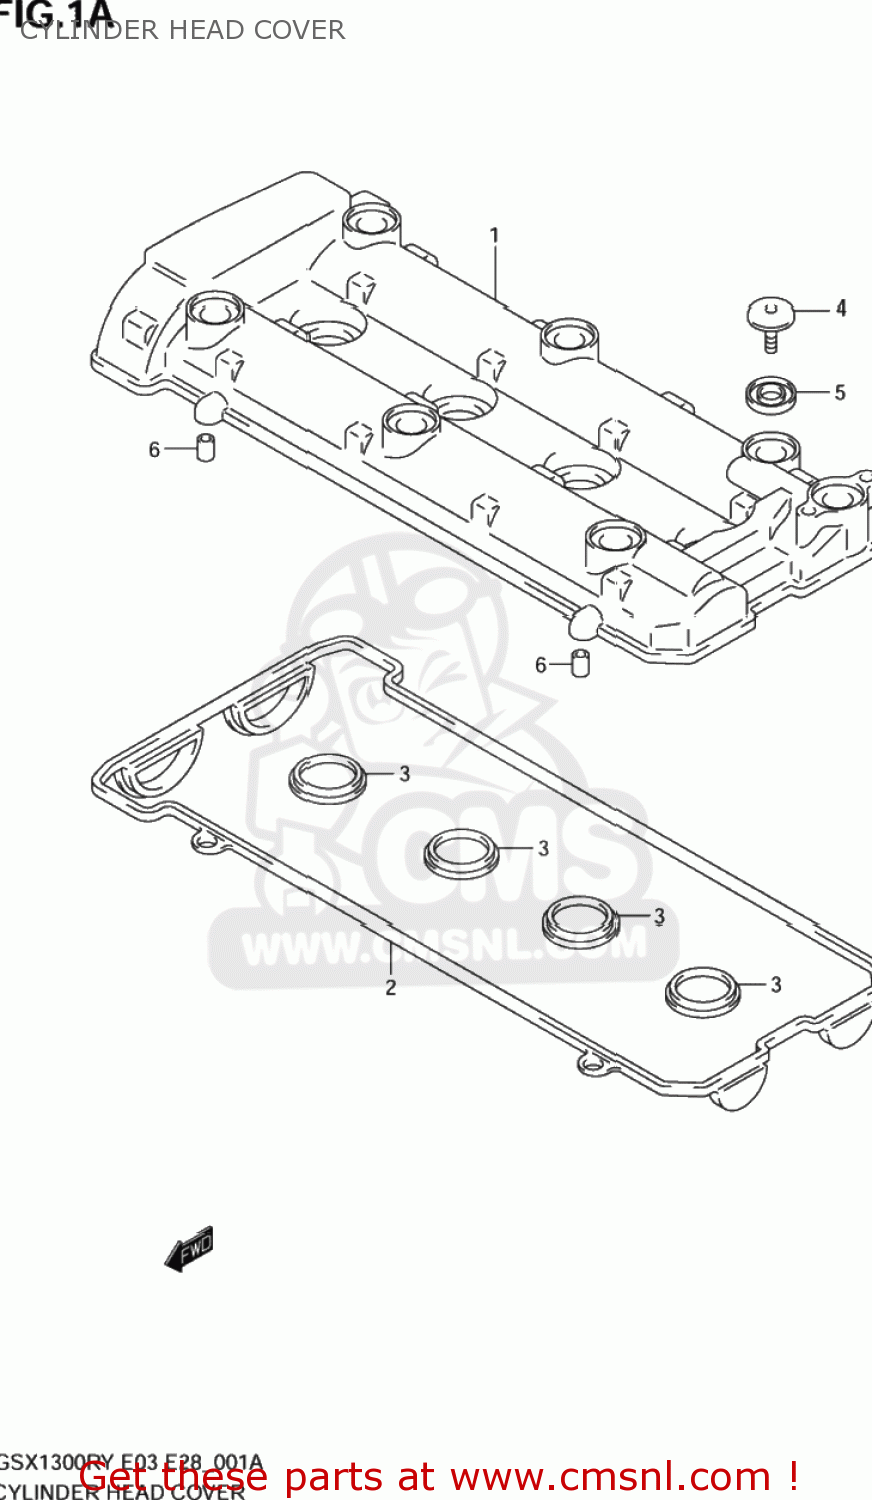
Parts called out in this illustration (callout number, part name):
1	COVER,CYLINDER HEAD
2	GASKET,CYL HEAD COVER NO.1 (NAS)
3	GASKET,CYL HEAD COVER NO.2
4	BOLT(7X17.5)
5	WASHER(10.6X25.5X2.3)
6	PIN
